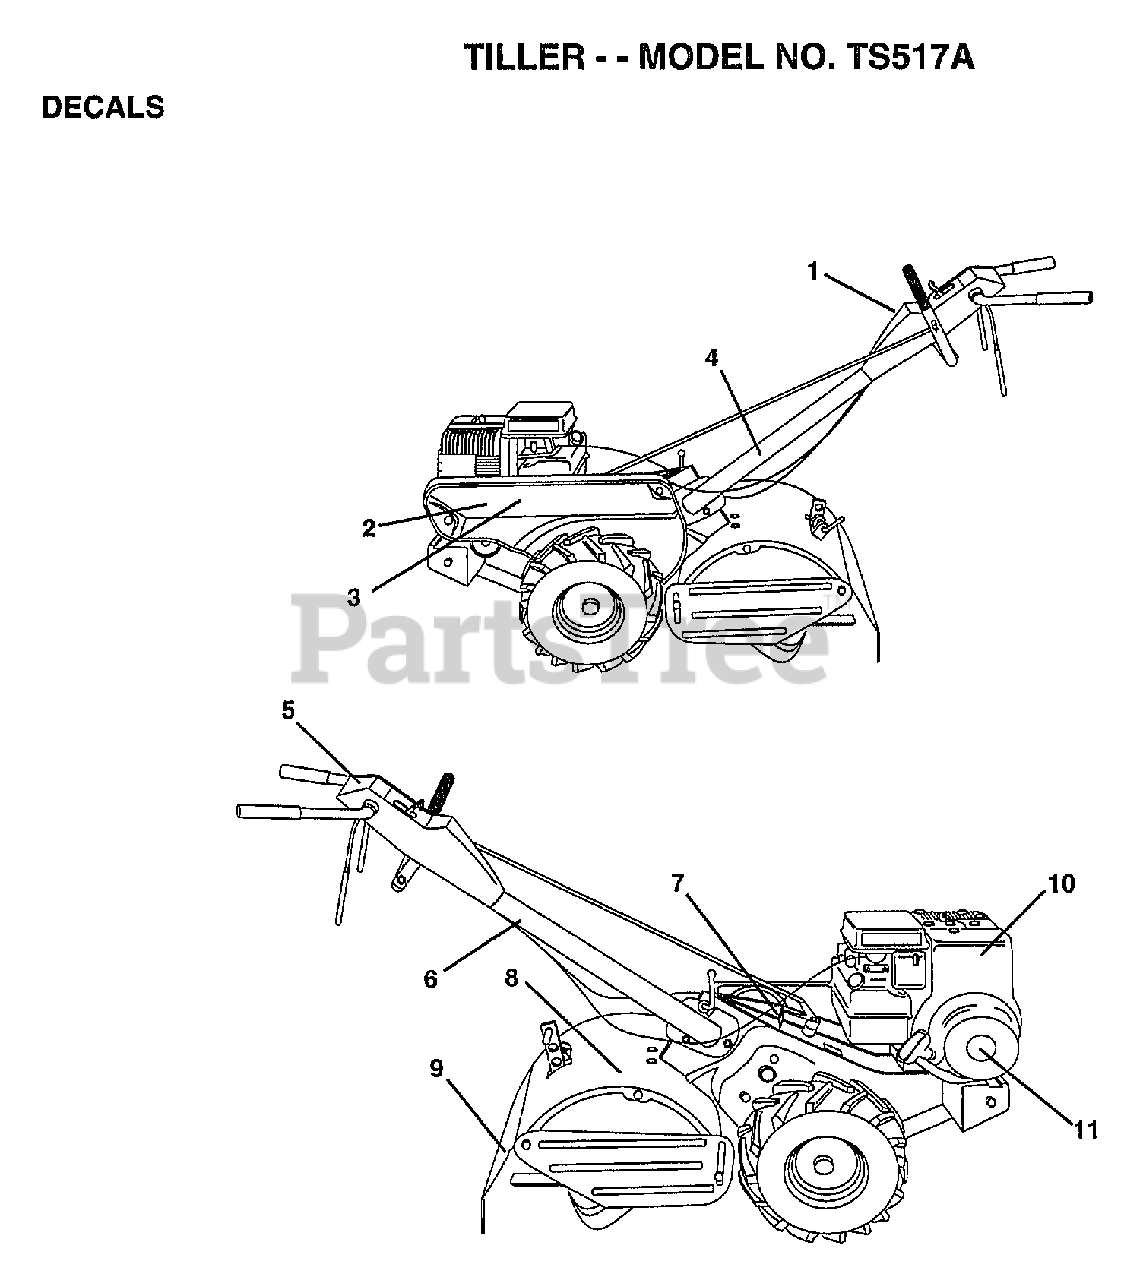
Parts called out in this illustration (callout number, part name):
1	DECAL.PNL.CTRL.
2	DECAL.GUARD.HUSKE
3	NAMEPLATE.HUSKEE
4	DECAL.BAR.USA.HUS
5	DECAL.INSTRUCTION
6	DECAL TI
7	DECAL CRT
9	DECAL TI
10	DECAL.ENG.B&S.5HP
11	DECAL.ENG.SML.5HP
